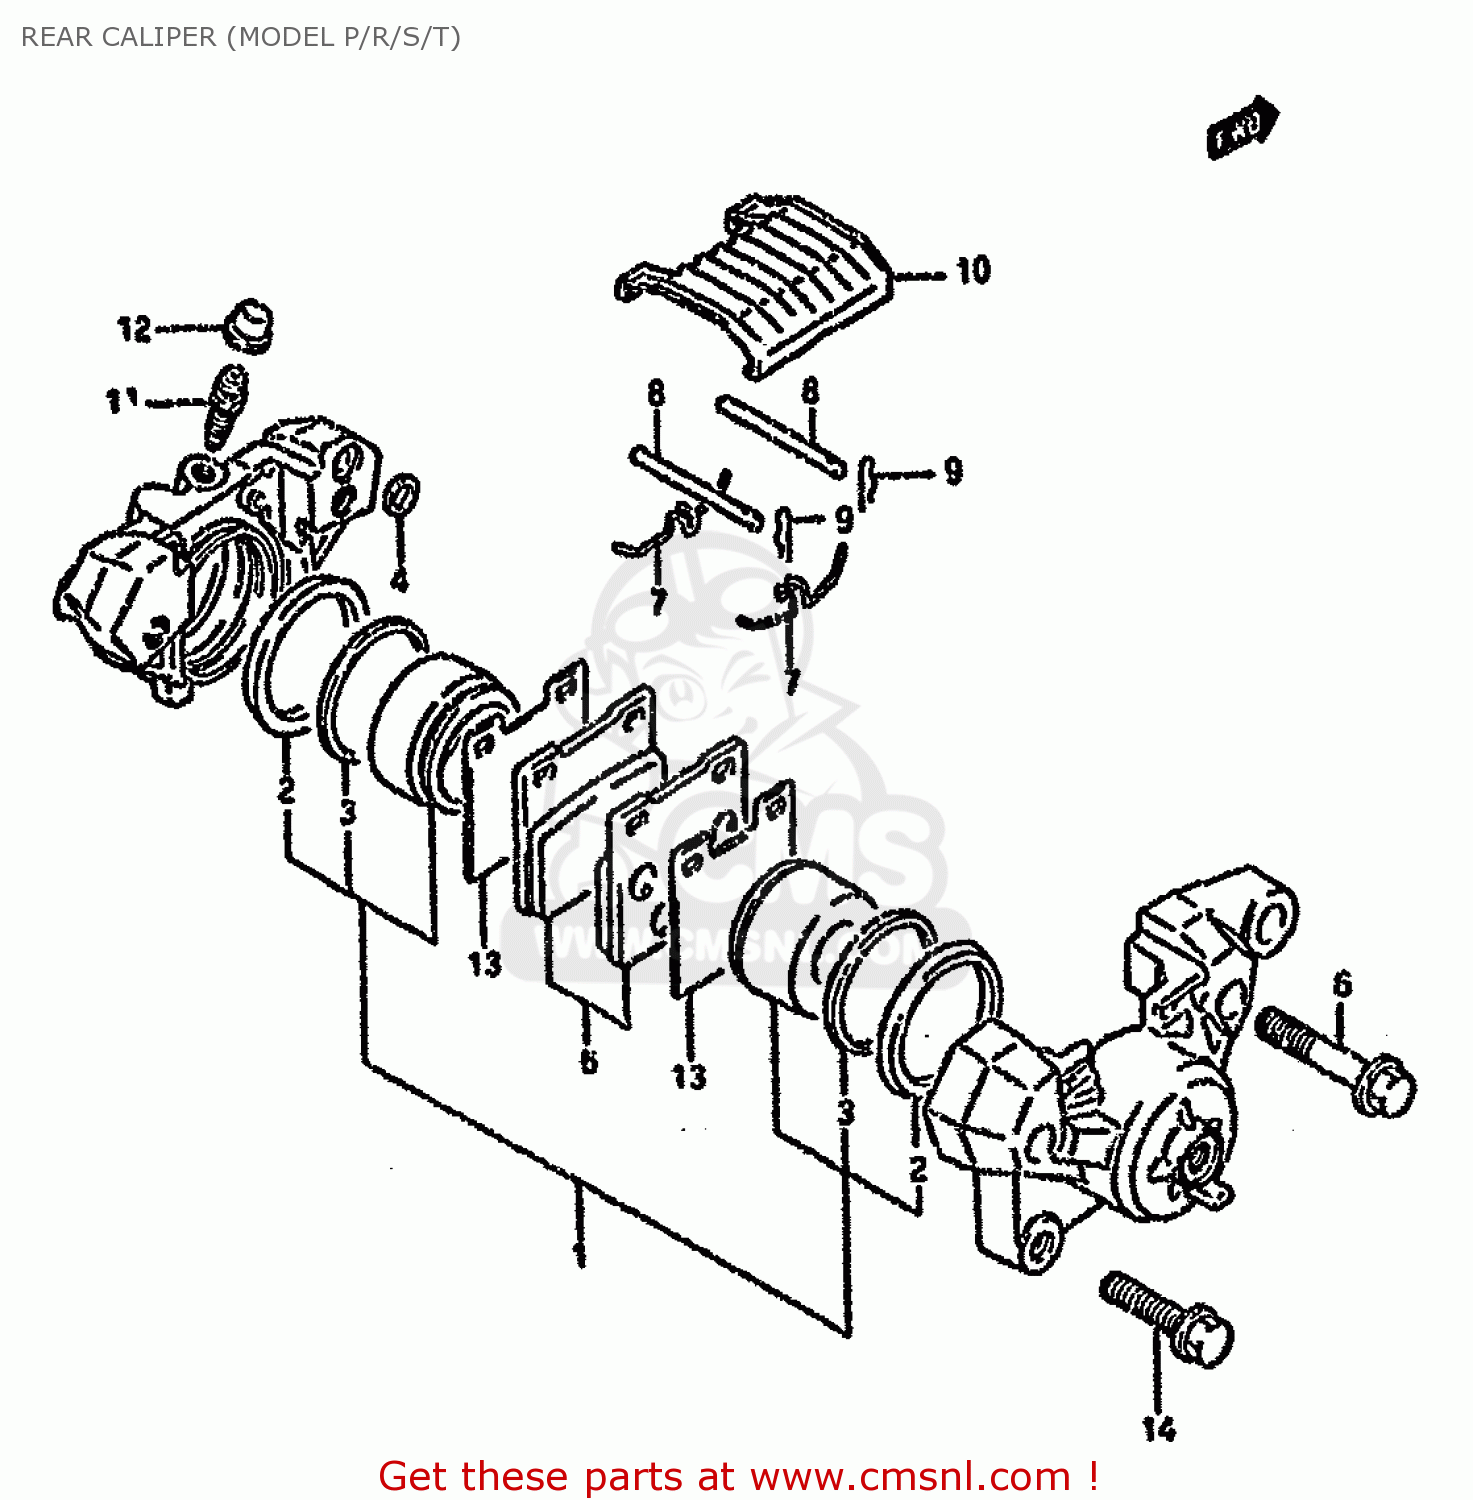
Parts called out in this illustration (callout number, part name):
1	PISTON SET
2	SEAL,PISTON
3	SEAL,WIPER
4	SEAL,JOINT
5	PAD SET (NAS)
6	BOLT
7	SPRING
8	PIN,PAD
9	CLIP,PAD PIN
10	COVER
11	BLEEDER
12	CAP,BLEEDER PLUG
13	SHIM,PAD
14	BOLT
